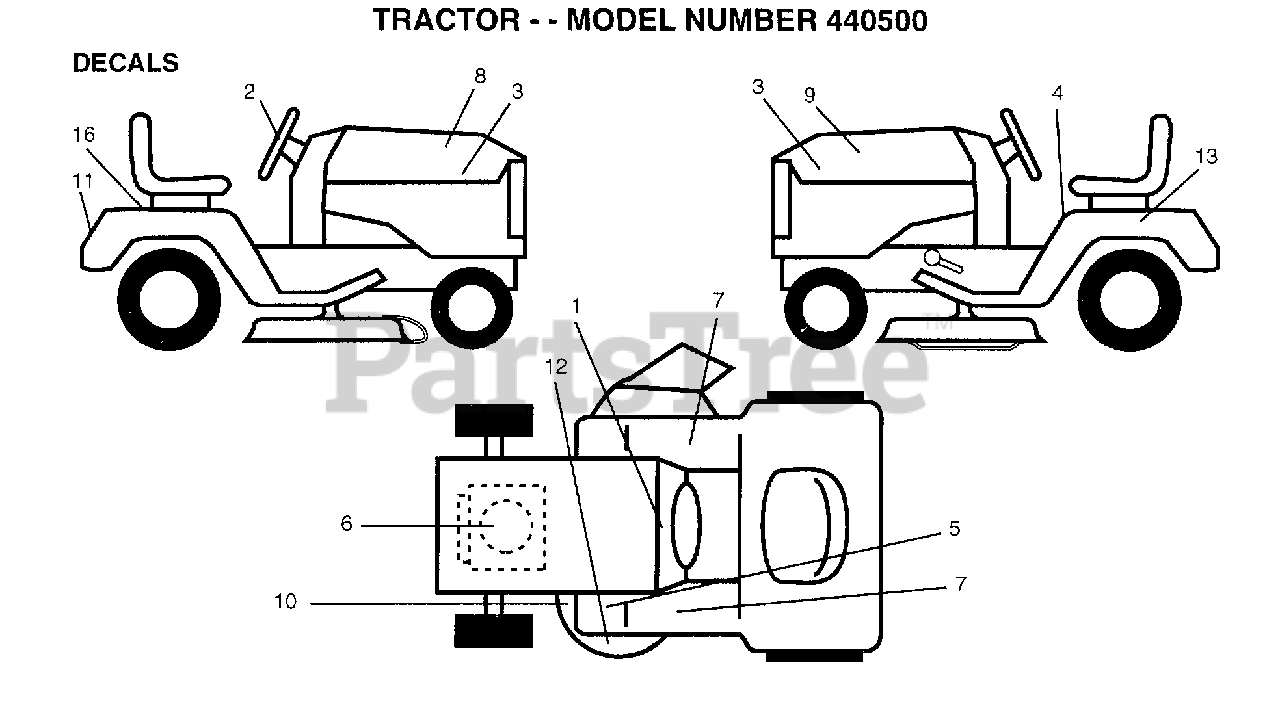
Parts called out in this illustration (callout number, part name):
2	DECAL.WHL.STRG.
3	DECAL.PHL SIDE
4	DECAL
6	DECAL, HP, ENGINE
7	FOOTREST PAD
8	DECAL. HOOD RH
9	DECAL HOOD LH
10	DECAL
11	DECAL.FENDER
12	DECAL.MOWER
13	DECAL.BTRY.DANGER
16	DECAL.FEND.QUICKS
